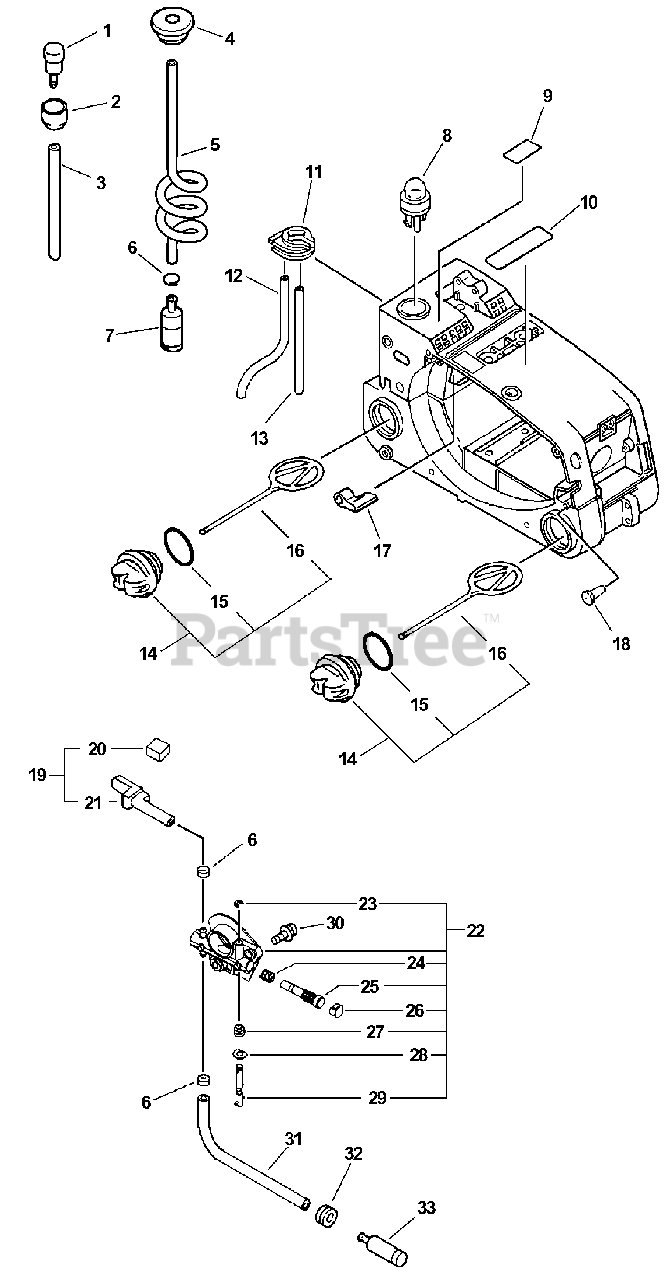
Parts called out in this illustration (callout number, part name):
1	VENT ASSY
2	HOLDER, VENT
3	PIPE, FUEL 3×5×100
4	GROMMET, FUEL
5	PIPE, FUEL 3×6×160
6	CLIP Ø6.5 MM
7	FILTER, FUEL
8	BULB, PURGE
9	LABEL, PURGE PUMP
10	LABEL - CAUTION
11	BRACKET, BULB
12	PIPE, FUEL 2×4×42 CLEAR
13	PIPE, FUEL 3x-5x-70 BLACK
14	CAP ASSY, OIL
15	O-RING 25
16	CONNECTOR, CAP L= 60 MM
18	VENT ASSY
19	PIPE KIT, OIL
20	PAD, FOAM
21	PIPE, OIL OUTLET
22	AUTO-OILER ASSY
25	PLUNGER ASSY
26	CAP, OIL PUMP
29	ADJUSTER, OILER
30	SCREW 5×12
31	PIPE 3×6×115 BLACK
32	GROMMET
33	FILTER, OIL
